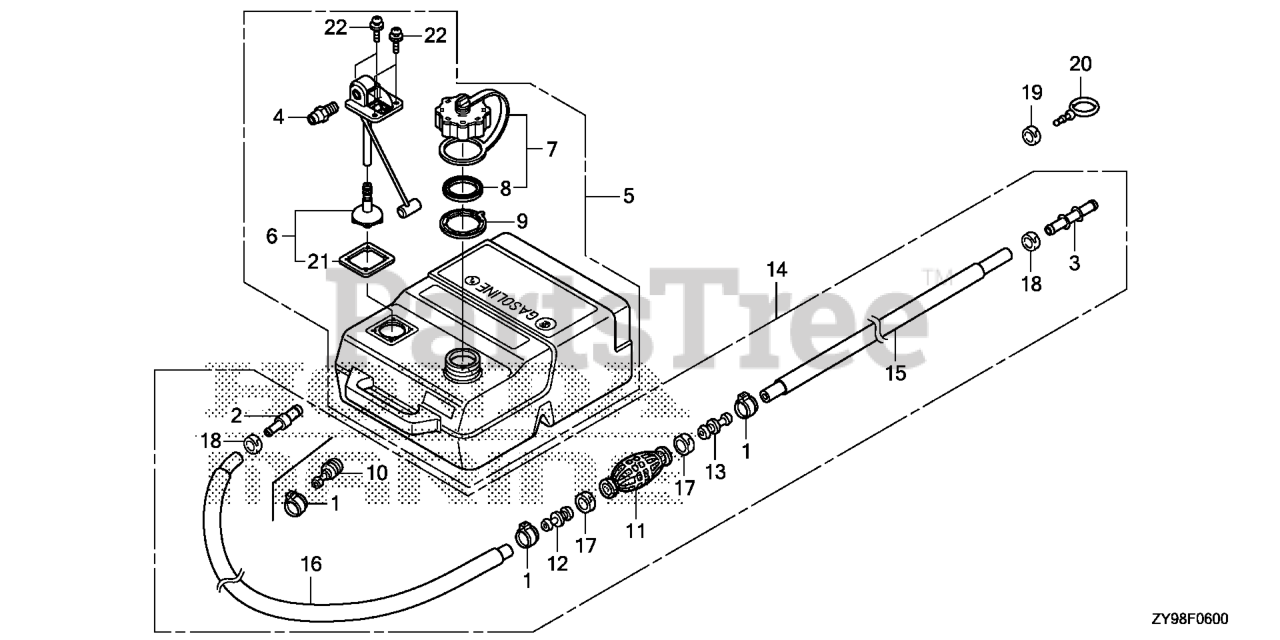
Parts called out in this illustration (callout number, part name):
1	CLAMP, FUEL TUBE (14.0) (CONNECTOR TYPE)
2	JOINT, FUEL TUBE (JOINT TYPE)
3	JOINT, FUEL TUBE
4	FITTING, QUICK DISCONNECT Use from Frame SN 1205705.
5	TANK ASSY., FUEL
6	FILTER KIT, FUEL
7	CAP, FUEL FILLER
8	GASKET, FUEL CAP
9	RETAINER, PRESSURE RELIEF
10	CONNECTOR, FUEL (CONNECTOR TYPE)
11	BULB, PRIMER
12	VALVE, IN.
13	VALVE, OUTLET
14	TUBE, FUEL TANK
15	TUBE, FUEL LONG (75)
15	TUBE, FUEL LONG (7.3X2000)
15	TUBE, FUEL SHORT
15	TUBE (75)
16	TUBE, FUEL LONG (75)
16	TUBE, FUEL LONG (7.3X2000)
16	TUBE, FUEL SHORT
16	TUBE (75)
17	BAND, TUBE CLIP (20MM)
18	BAND, TUBE CLIP (12.5MM)
19	BAND, TUBE CLIP (12.5MM)
20	PLUG, FUEL TUBE
21	GASKET, FUEL PICK-UP
22	BOLT-WASHER (5MM) (SEAL)
